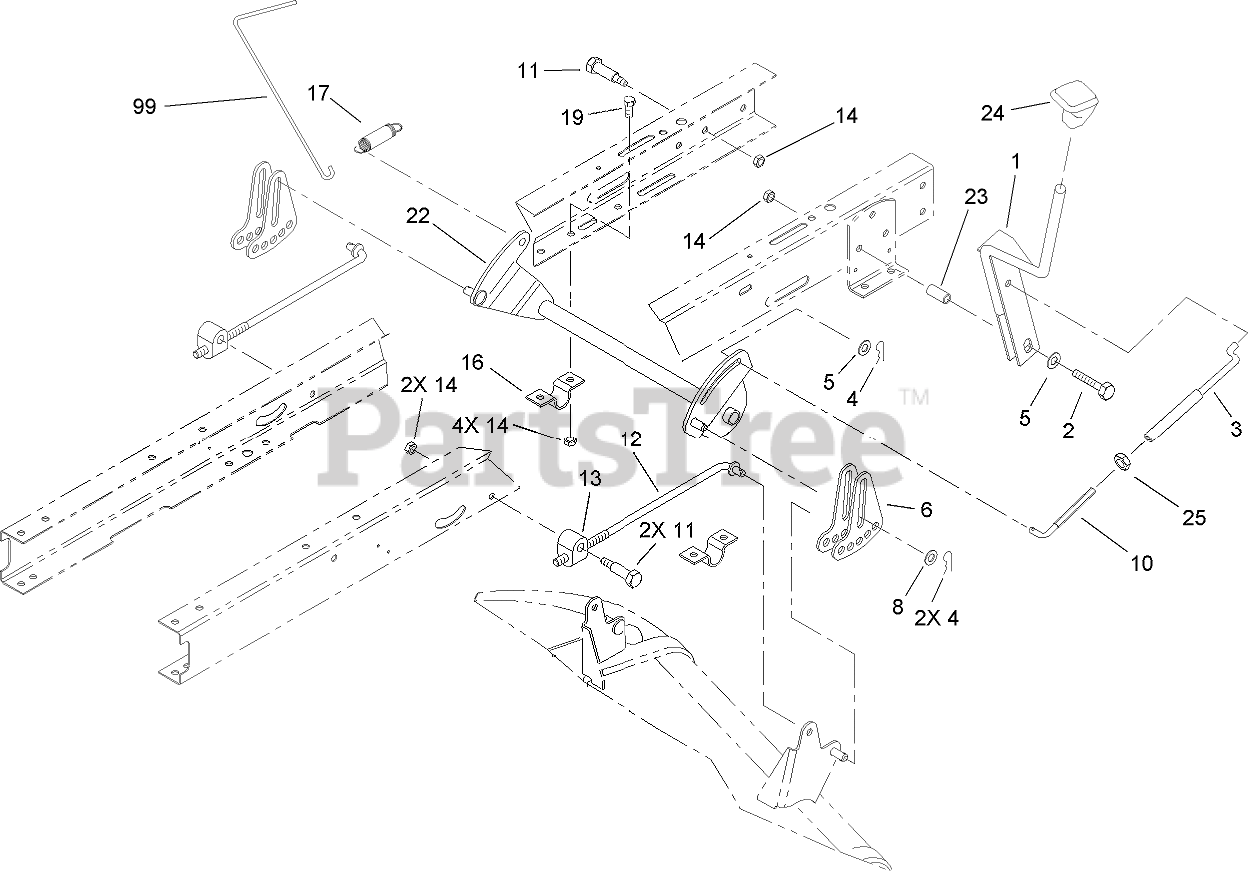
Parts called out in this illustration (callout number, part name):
1	HOC LEVER ASM
2	SCREW-HH
4	PIN-COTTER
5	WASHER-FLAT
6	LINK-ADJUSTING, HOC
8	WASHER-HARDENED
10	LINK-HOC
11	SCREW-SHOULDER, HH
12	ROD-HANGER, REAR
13	TRUNNION-HOC
14	NUT-LOCK, NI
16	CLAMP-PIVOT, HOC
17	SPRING-EXTENSION
19	SCREW-HH
22	PIVOT-HOC
23	SPACER
24	KNOB-SHIFT
25	NUT-JAM
